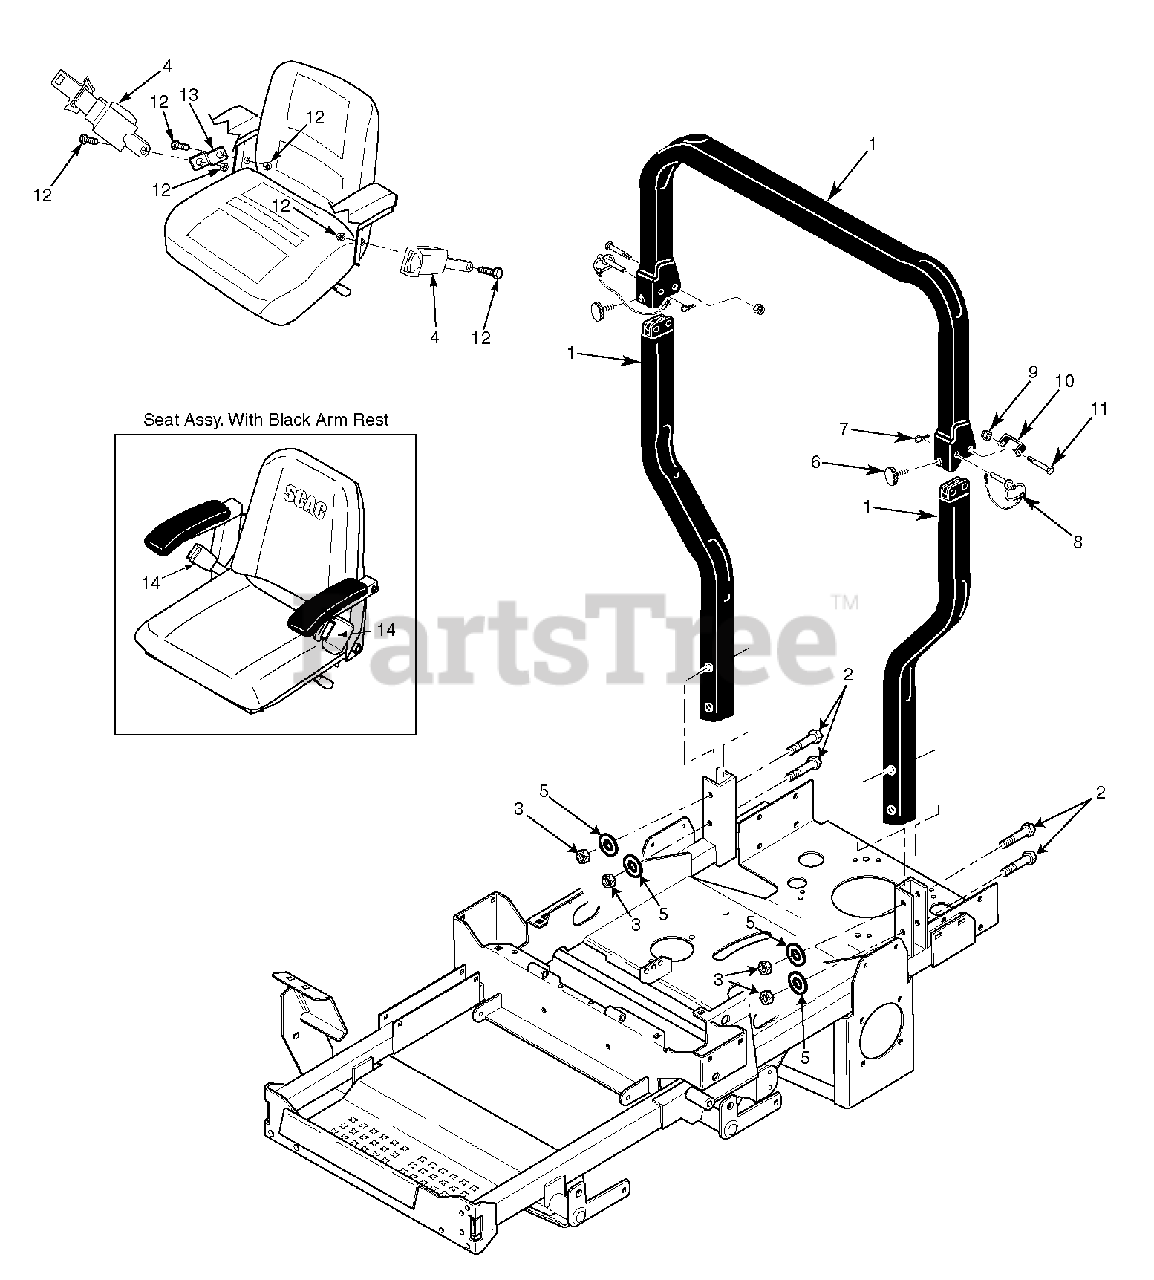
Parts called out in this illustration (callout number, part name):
1	STC Foldable ROPS Accessory
2	Bolt, Hex Head 1/2-13 x 3-1/2"
3	Nut, Center Lock 1/2-13
4	Retractable Seat Belt
5	Flatwasher, 1/2-.562 x 1.375 x .109"
6	Thumb Screw, 5/16-18 NC x 3/4"
7	Hair Pin, Cotter
8	Pin
9	Nut, Center Lock 1/2-13
10	Bracket, Stop
11	Bolt, Hex Head 1/2-13 x 3-1/2"
12	Seat Hardware Kit, STC
13	Bracket
14	Retractable Seat Belt (Seat with Black Armrest)
14	Hardware Package, Seat Belt Mounting
